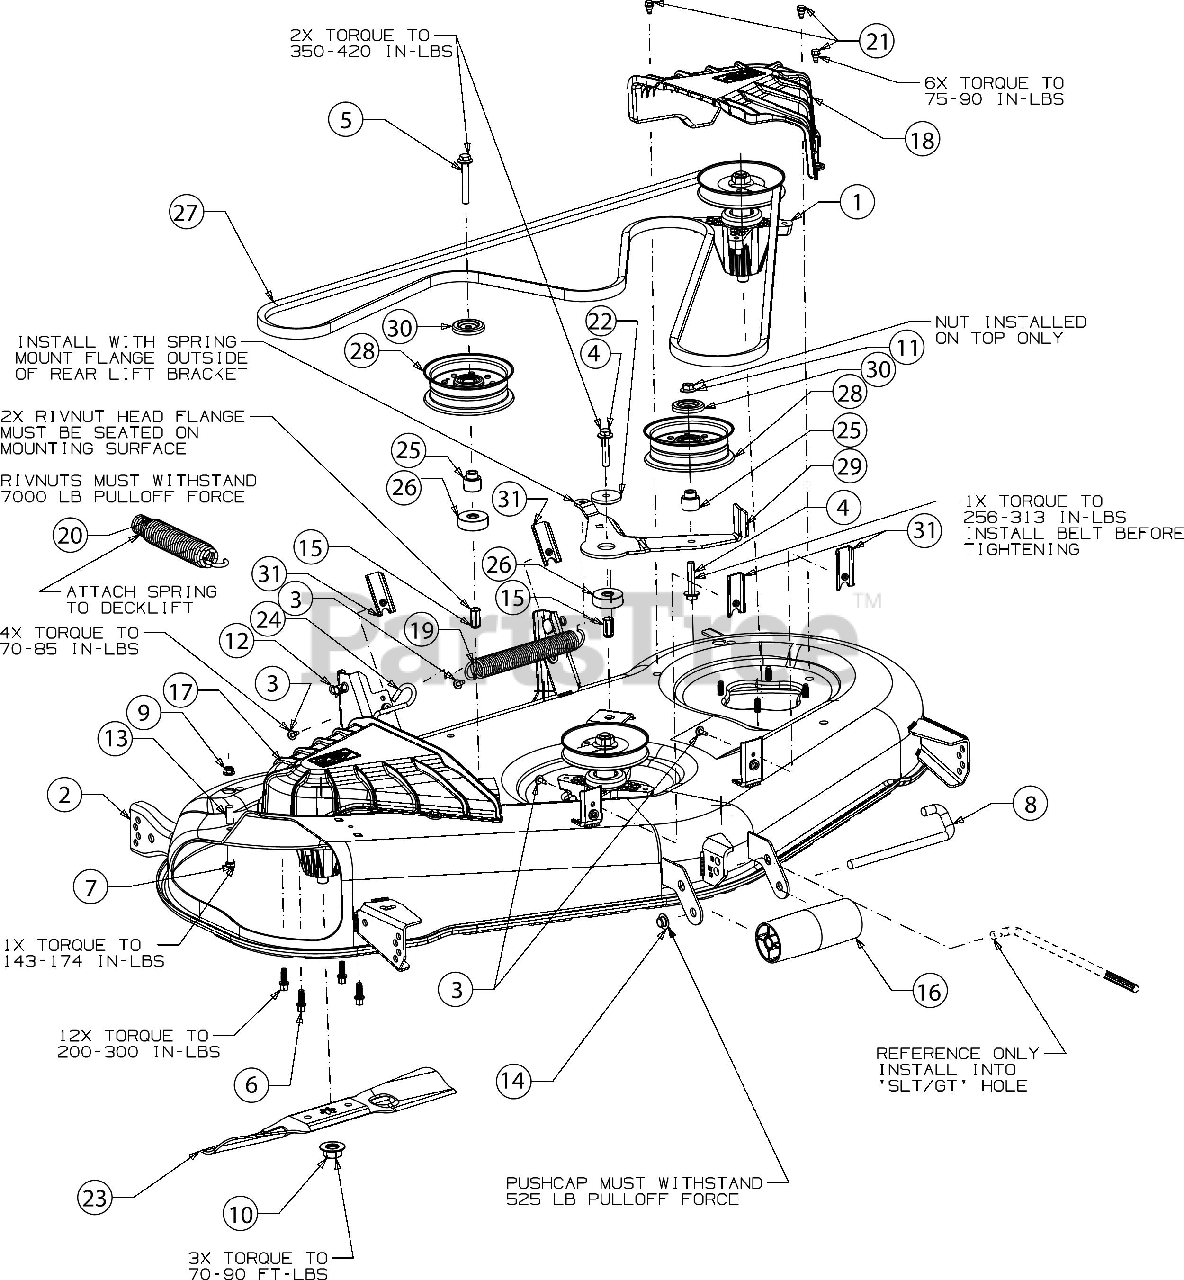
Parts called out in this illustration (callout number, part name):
1	SPINDLE ASSEMBLY
2	50" DECK SHELL
3	SCREW M6-1 x .625
4	SCREW 3/8-16 x 2.0
5	SCREW 3/8-16 x 2.75 GR5
6	SCREW 5/16-18 X .875
7	SCREW 5/16-18 x 1.5 LG
8	ROLLER PIN 1/2 x 7.31
9	FLANGE LOCK NUT 5/16-18
11	FLANGE LOCK NUT
12	BOW TIE COTTER PIN
15	NUT RIVET 3/8-16
17	SPINDLE COVER (RH)
18	SPINDLE COVER (LH)
19	EXTENSION SPRING
20	LIFT ASSIST SPRING
21	SHOULDER SCREW 1/4-20 x .50
22	SHOULDER SPACER
23	17.27" BLADE (2N1)
24	DECK SPRING HOOK
25	SHOULDER SPACER
26	SPACER .385ID x 1.75OD x .585THK
27	V-BELT B SEC x 134
28	IDLER PULLEY 4.50" DIA
29	IDLER PIVOT BRACKET 50/54
30	IDLER PULLEY CAP
